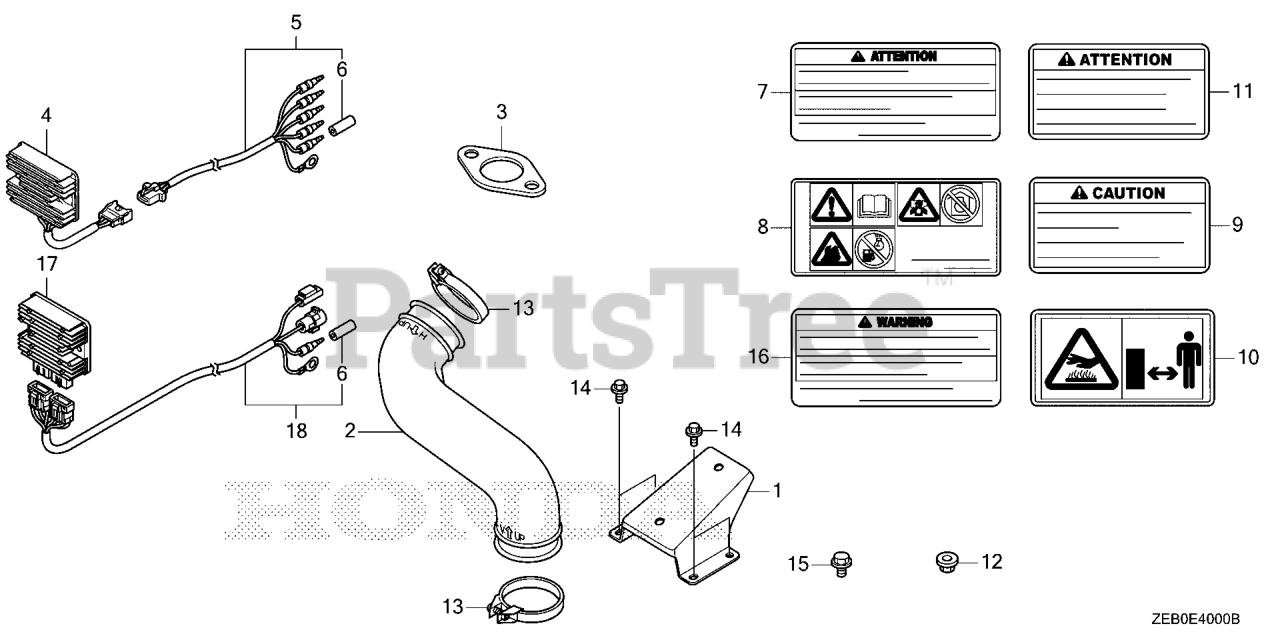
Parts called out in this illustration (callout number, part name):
3	GASKET, EX. PIPE
4	RECTIFIER ASSY., REGULATOR (17A)
5	SUB-WIRE HARNESS ASSY.
6	PLUG, CONNECTOR (OUTER) (ENGINE NO.)
7	MARK, OPERATOR CAUTION (FRENCH)
9	MARK, EX. CAUTION (ENGLISH)
10	MARK, EX. CAUTION (PICTOGRAPH)
11	MARK, EX. CAUTION (FRENCH)
12	NUT, FLANGE (8MM)
16	MARK, OPERATOR CAUTION (ENGLISH)(MADE IN CHINA)
